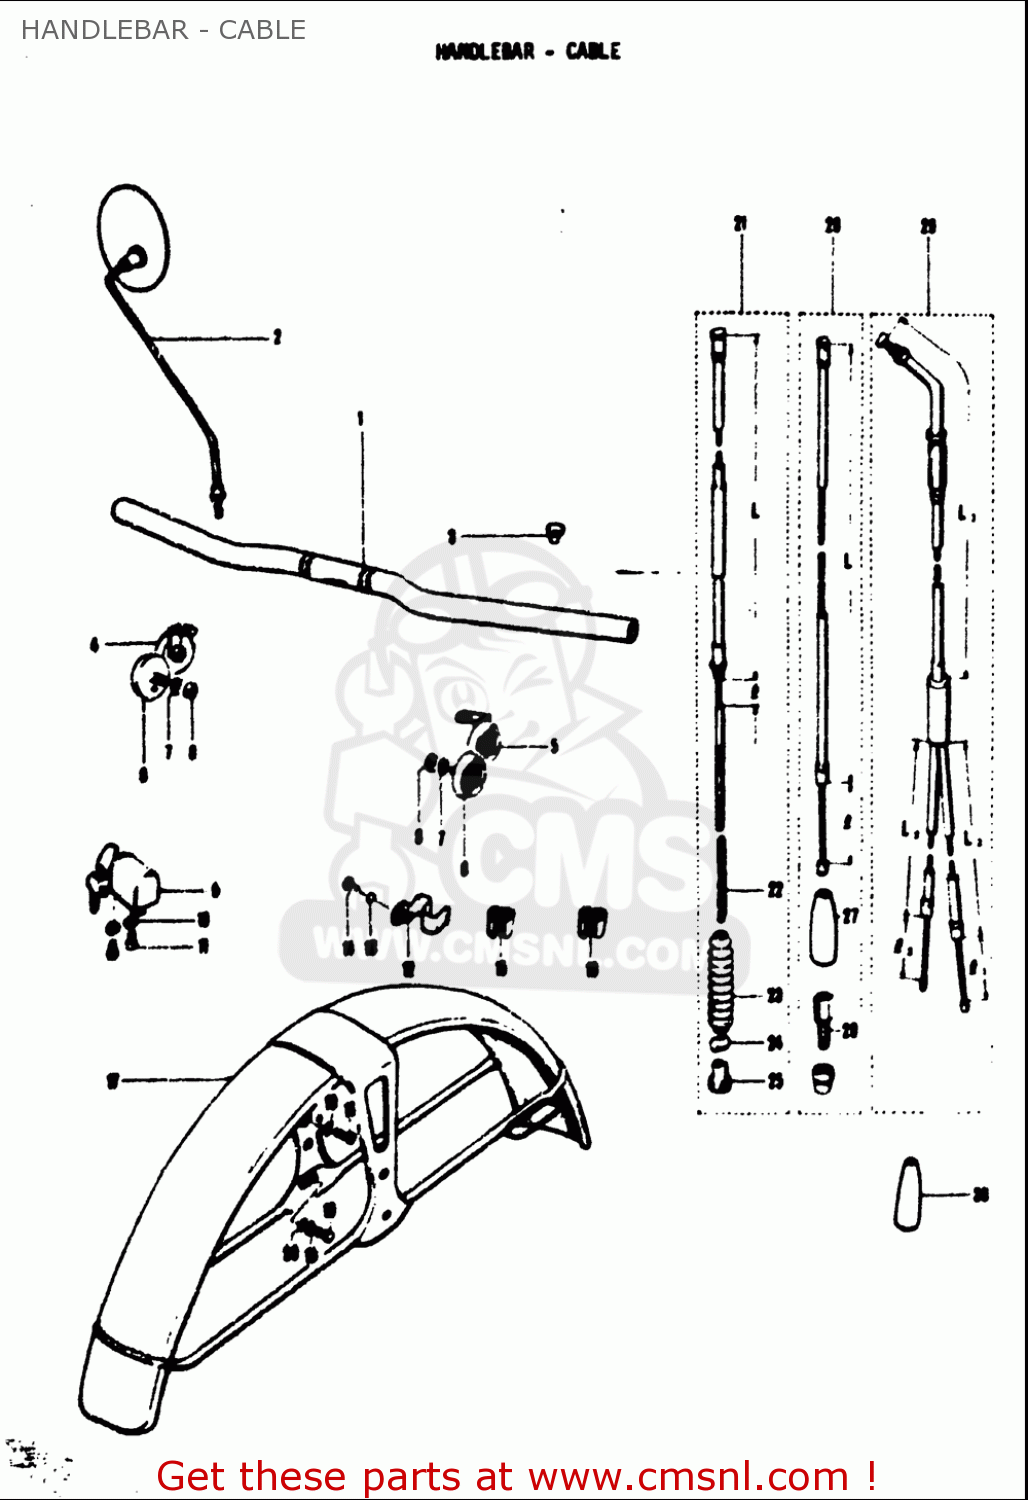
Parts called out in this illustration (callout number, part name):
3	CAP
7	WASHER,LOCK
8	NUT
10	WASHER,LOCK
11	SCREW
13	WASHER,LOCK
14	BOLT
15	CLIP
16	CLIP
19	WASHER,LOCK
20	WASHER
21	CABLE ASSY,FR BRAKE
22	SPRING
23	SEAL,DUST(7X16X75)
24	BRAKE ROD LEVER
25	BRAKE ROD ADJ N
28	NUT
30	SEAL,DUST(7X18X30)
